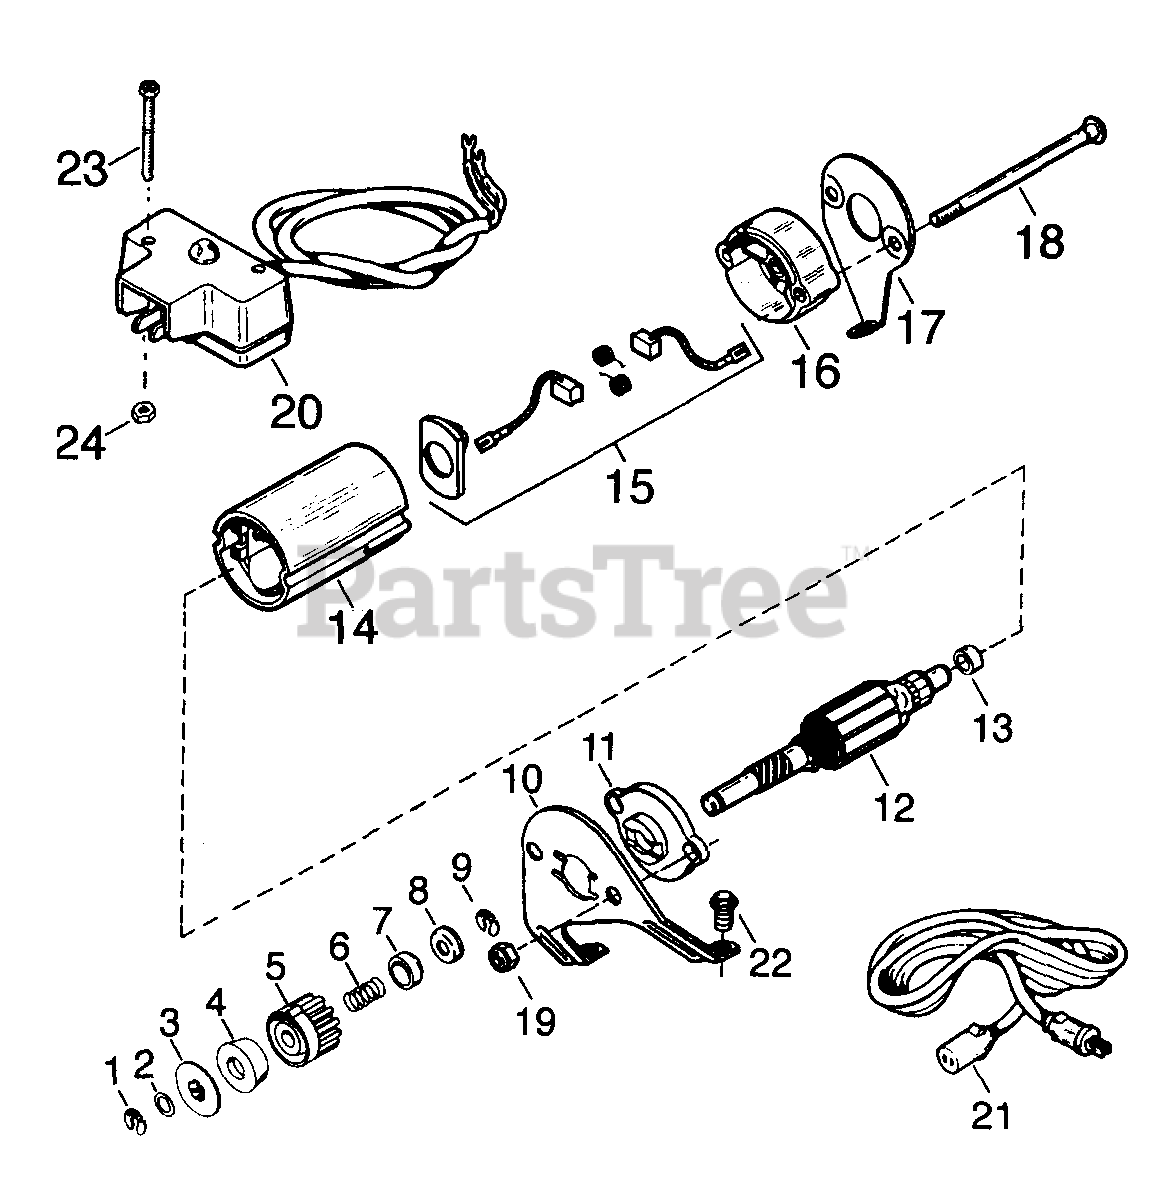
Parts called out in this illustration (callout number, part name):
1	Retainer Ring
2	Dust Washer
3	Pinion Driver
4	Anti-drift Spring
6	Anti-drift Spring
7	Spring Retainer
8	Cup Washer
9	Retainer Ring
10	Drive End Mounting Bracket
11	Drive End Cap Assy
13	Thrust Spacer
14	Housing Assy
15	Brush & Spring Card Assy
16	Commutator End Cap Assy
17	Commutator End Mounting Bracket
20	Switch Box & Lead Assy
21	Extension Cord
22	Screw, Torx T-30, 1/4-20 x 1/2"
23	Screw, 6-32 x 2-1/2"
24	Nut Washer Assy
